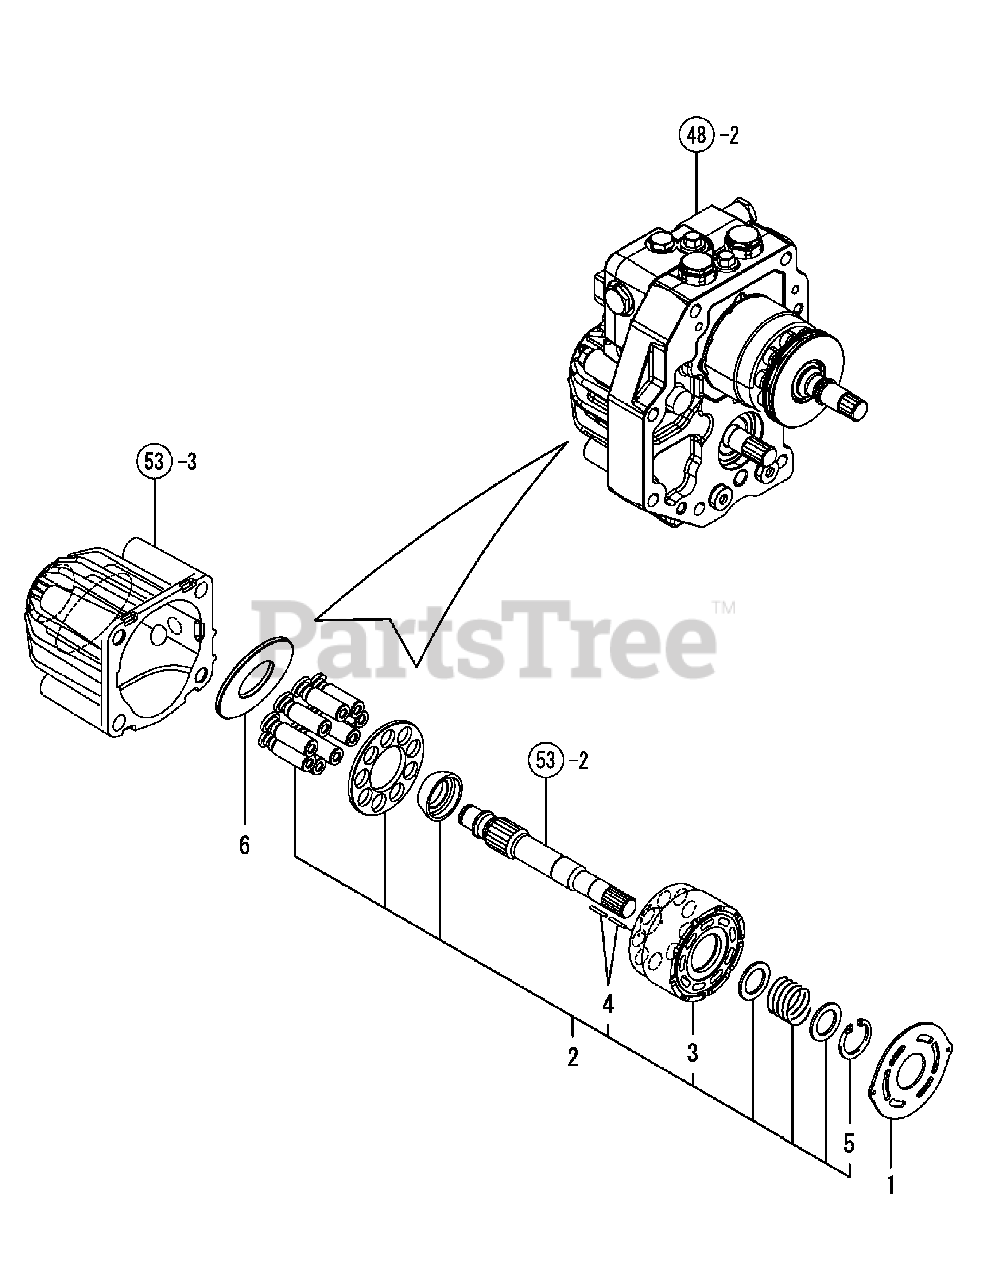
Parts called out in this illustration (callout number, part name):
1	Valve Plate (M
2	Block Assy, Cyl, HST
3	Block, Cylinder, HST
